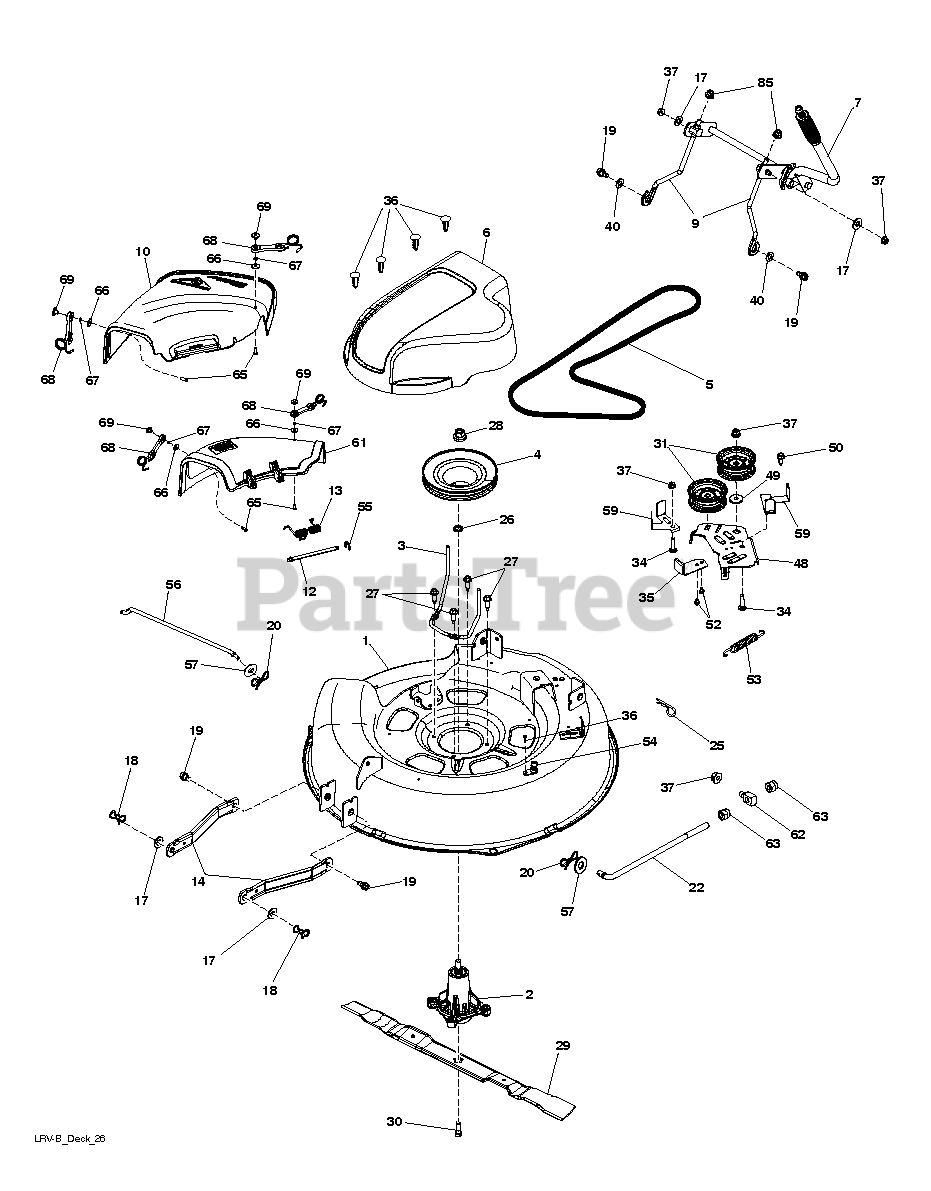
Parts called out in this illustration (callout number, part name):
1	DECK.PNT.LRV.30
2	MANDREL.ASM.SUB-NON.GR
3	Belt Keeper, Gen2 Mandrel
4	Mandrel Pulley, LRV GENS
5	Belt, 30
6	COVER.MANDREL.30".LRV.(B)
7	LIFT.SUBASM.DECK
9	LINKAGE LRVB GEAR DRIVE X431
10	DEFLECTOR ASSEMBLY
12	PIN.HINGE
13	SPRING.DOUBLE.TORSION.SPRING
14	FRONT.DECK.LINK.PNT
17	WASHER.CLEAR.ZINC
18	PIN.COTTER.7/16.BOW TI.
19	BOLT.SHOULDER
20	PIN.COTTER.5/16.BOW TI
22	LINK.LRVB.30".FRONT.DECK.ADJ
26	WASHER.SPACER.MANDREL
27	SCREW, WASHER HEAD
28	NUT.FLANGE.LOCK.TOP
29	BLADE, MULCH.LRV30
30	BOLT.WASHER.ASM.7/16-2
31	PULLEY.IDLER.48"PRIMARY
34	BOLT.3/8-16X1.50
35	ARM BRAKE MOWER RH
36	SCREW.1/4-20X5/8
37	NUT LOCK FLG 3/8-16 UNC
49	SPACER.RETAINER
50	SCREW 3/8-16X1
52	SCREW 1/4X20
53	SPRING.LRVB.CLUTCH.ARM
54	PORT.WASHOUT
55	E-RING.5/16"
56	ROD.ANTI.SWAY.48/54"K4
57	WASHER
59	GUARD.TUV.IDLER.42
61	MULCH.COVER.ASSEMBLY.30"
62	TRUNNION
63	NUT, LIFT LINK 7/16-20
67	LOCKWASHER
68	LATCH ASSY
69	NUT.WELD.#10-24 (2 2)
85	NUT
